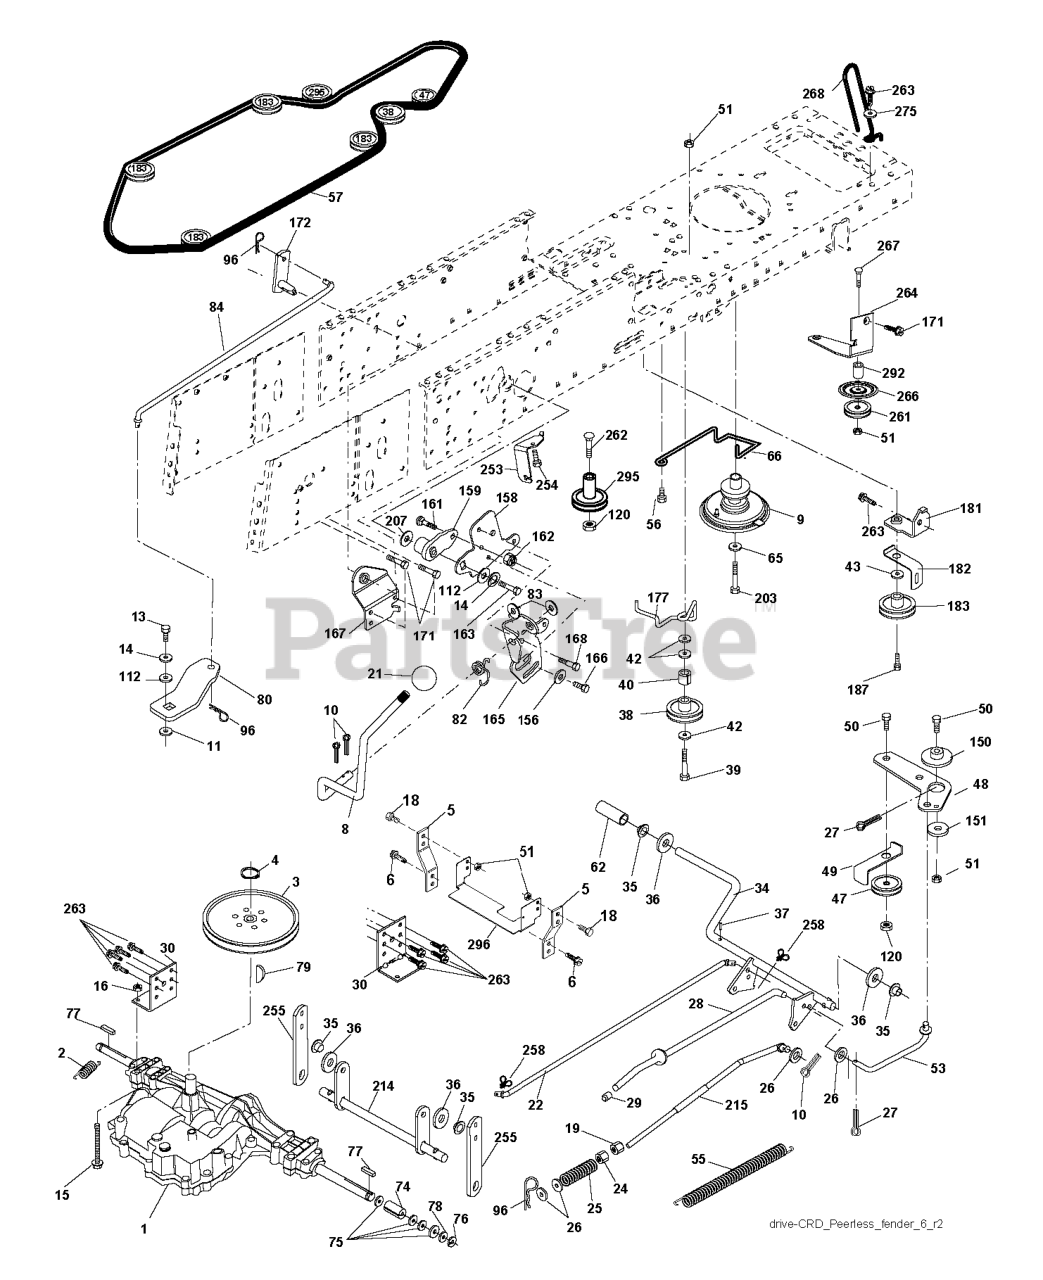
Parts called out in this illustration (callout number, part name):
2	SPRING,BRAKE RETURN
3	PULLEY
4	RETAINING RING LT
5	STRAP TORQUE
6	SCREW 5/16"
8	ROD SHIFT FENDER ADJUST LT
9	CLUTCH.ELECTRIC.OGURA.EURO.
10	PIN COTTER
11	WASH-SHFT PLT LT
13	BOLT 1/4-28X3/4
14	LOCKWASHER
15	BOLT HEX 5/16-18 GR 5
16	NUT.71038.31-18.HEX.NYLOCK
19	NUT
20	BOLT HEX 7/16-20X4-1/4"
21	KNOB.DUCKHEAD.1/2
22	ROD
24	NUT
25	SPRING ROD LT
26	WASHER
27	COTTER PIN
28	ROD, PARKING BRAKE
29	CAP
30	BRKT, MOUNT TRNSAXLE
34	SHAFT, FOOT PEDAL
35	BEARING.NYLON
37	DRIVE PIN
38	PULLEY.FLAT
42	WASHER
47	IDLER PULLEY
48	BELLCRANK, CLUTCH
49	RETAIN BELT
50	BOLT.3/8-16X1.50
53	LINK.CLUTCH.7.66.2005
55	SPRING, RETURN LT
56	SCREW.3/8-16
57	V-BELT.KEV.111"
62	PEDAL COVER T
63	PULLEY.ENGINE.CVX.LT
65	LOCKWASHER
66	KEEPER BELT ENGINE
74	SPACER AXLE
77	SQUARE KEY
79	KEY STD (1373) DANA
82	SHIFT SPRING
83	WASHER
96	RETAINER M
120	NUT LOCK FLG 3/8-16 UNC
150	BUSHING.BELLCRANK.GRD.DR
151	WASHER 12/32X2X10GA
156	WASHER.SRRTD.5/16
158	BRACKET
159	RB HUB.SHIFT
161	BOLT
162	NUT.CROWNLOCK.1/4
165	RP BRACKET
166	CAPSCREW.HXHD.FLG.5/16-18X.625
167	BRACKET.SUPT.SHIFT.CRD
168	BOLT.SHOULDER.5/16-18X
172	SHAFT
181	BRACKET
182	BELT GUIDE
183	PULLEY.V-IDLER.GRND.DR
187	BOLT.5/16-18X1.25
207	WASHER NYL
214	LEVER
243	BRACKET, ANTI-ROTATION
254	SCREW 3/8-16X1
255	SHAFT
258	CLIP RETAINER
261	FLAT IDLER PULLEY
263	SCREW, 3/8-16X3/4
266	PROTECTOR
268	GUARD MUFFLER
275	WASHER
292	SPACER
295	PULLEY IDLER COMPOSITE
